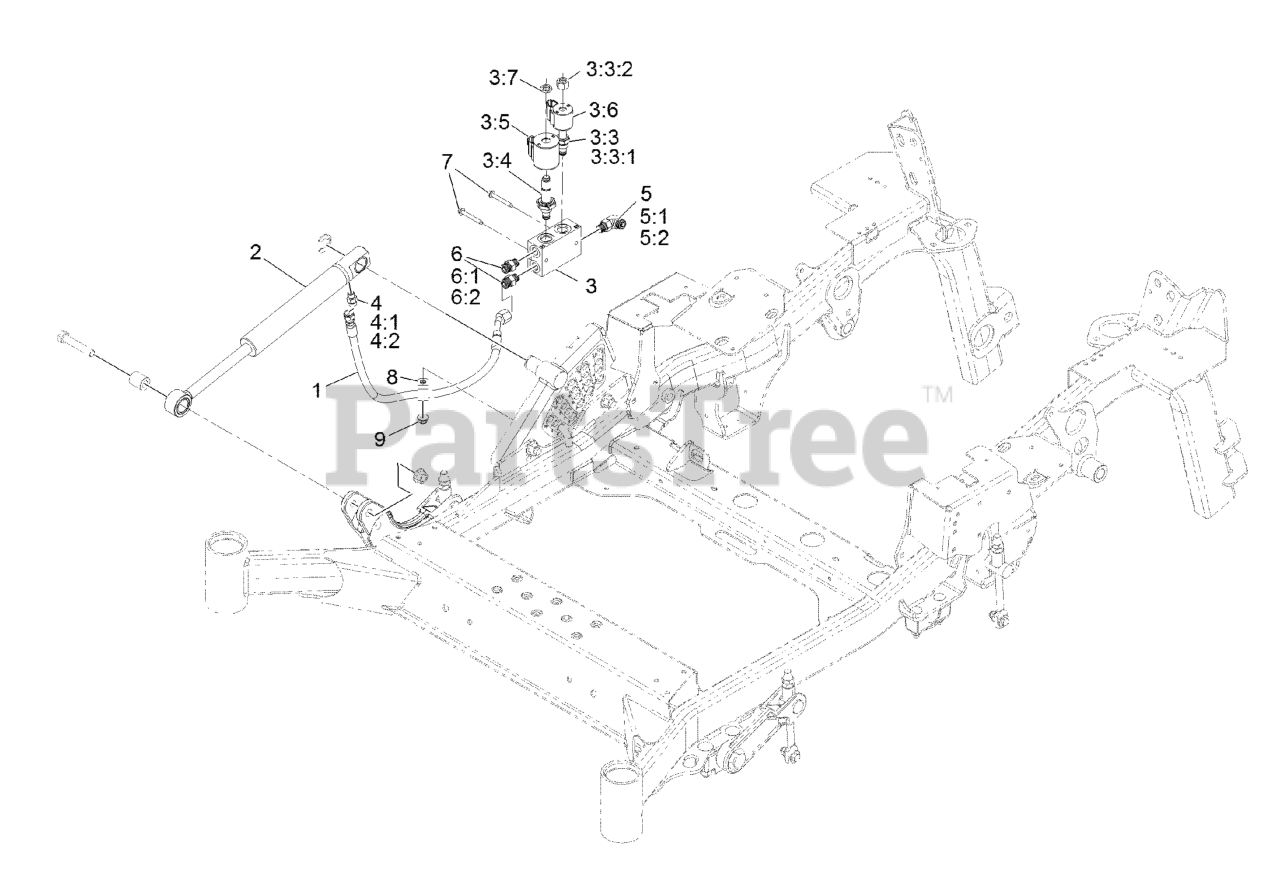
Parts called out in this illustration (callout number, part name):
1	HOSE ASM
2	CYLINDER-LIFT
3	DECK LIFT VALVE ASM
3:3	VALVE-SOLENOID
3:3:1	SEAL KIT
3:3:2	NUT-SOLENOID
3:4	VALVE-SOLENOID
3:5	COIL-12V
3:7	NUT-COIL
4	FITTING-HYD, STRAIGHT
4:1	O-RING
4:2	O-RING
5	FITTING-ELBOW, 90 DEG
5:1	O-RING
5:2	O-RING
6	FITTING-STRAIGHT
6:1	O-RING
6:2	O-RING
7	SCREW-HWHTF
8	CLIP-LOOM
9	NUT-HF, NI
